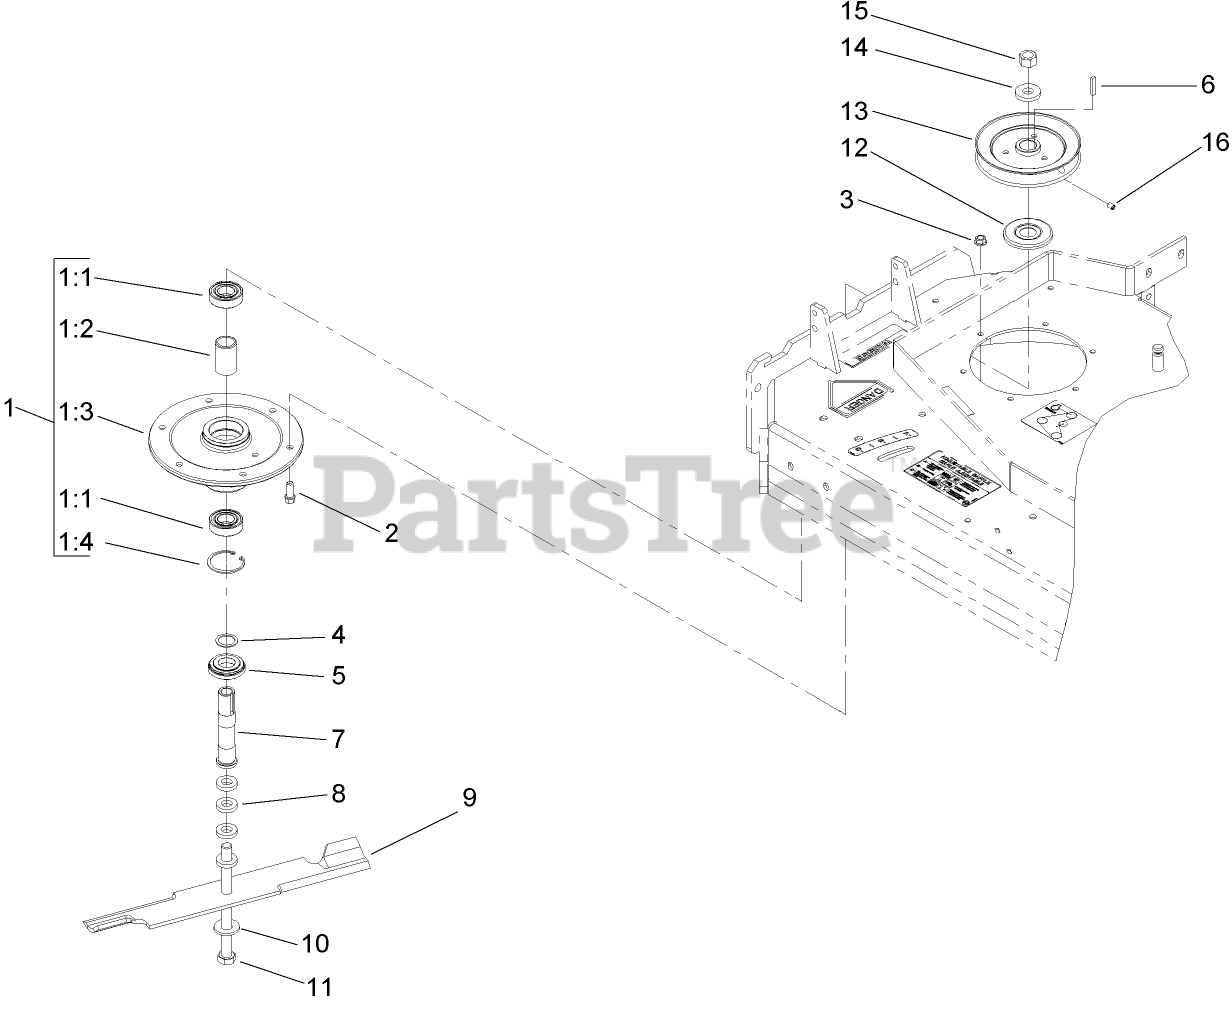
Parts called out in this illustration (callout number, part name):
1	SPINDLE HOUSING ASM
1:1	BEARING
1:2	SPACER-BEARING
1:3	HOUSING-SPINDLE
1:4	RING-SNAP
2	SCREW-HWH
3	NUT-HHF, WHIZ
4	WASHER-SPACER
5	SPACER-GUARD, BOTTOM
7	TUBE-SPINDLE, SHORT
8	SPACER
9	BLADE-Hi FLOW, 18 Inch
10	WASHER-SPRING
11	SCREW-CAP, HH
12	Guard-Bearing, Top
13	SHEAVE
14	WASHER-RETAINER, SHEAVE
15	NUT-HEX
16	SCREW-SET
